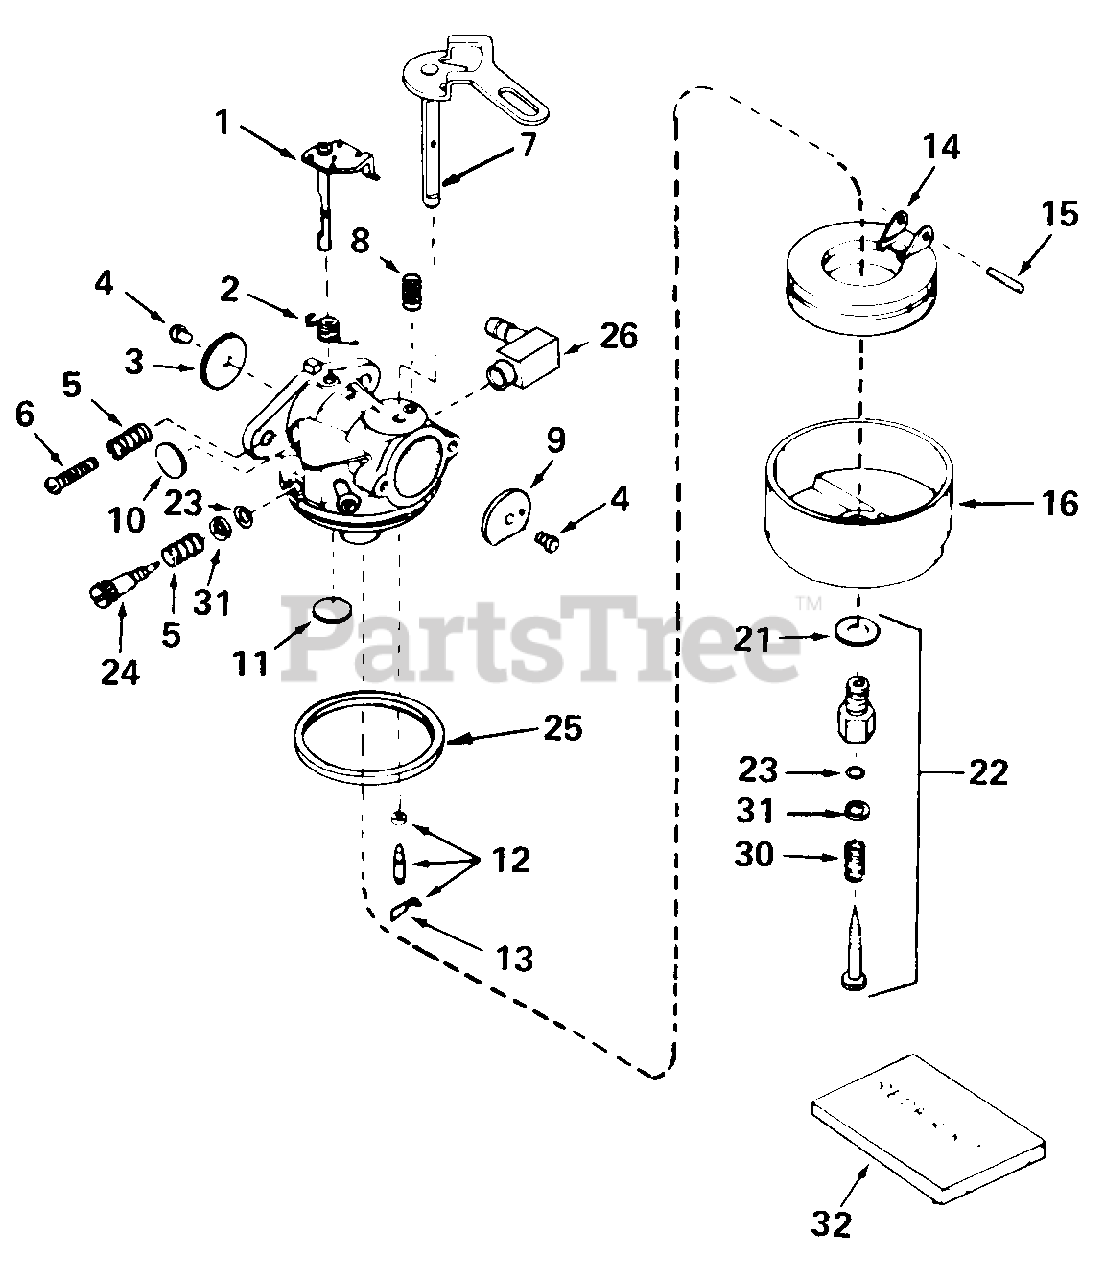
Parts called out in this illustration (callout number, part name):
1	Shaft & Lever Ass'y., Throttle
2	Spring, Throttle Return
3	Shutter, Throttle
4	Screw, 4-40 x 3/16
5	Spring, Idle Regulating Screw
6	Screw, Idle Regulating
7	Shaft & Lever Ass'y., Choke
8	Spring, Choke Stop
9	Shutter, Choke
10	Plug, Welch
11	Plug, Welch
12	Inlet Needle, Seat & Clip Ass'y.
13	Clip, Inlet Needle
14	Float, Carburetor
15	Shaft, Float
16	Bowl, Float
21	Gasket, Bowl-to-Body
22	Adjustment Screw Ass'y., Main
23	"O"-Ring, Adjustment Screw
24	Screw, Idle Adjustment
25	Gasket, Bowl-to-Body
26	Fitting, Fuel Inlet
30	Spring, Main Adjustment Screw
31	Washer, Flat
32	Repair Kit
